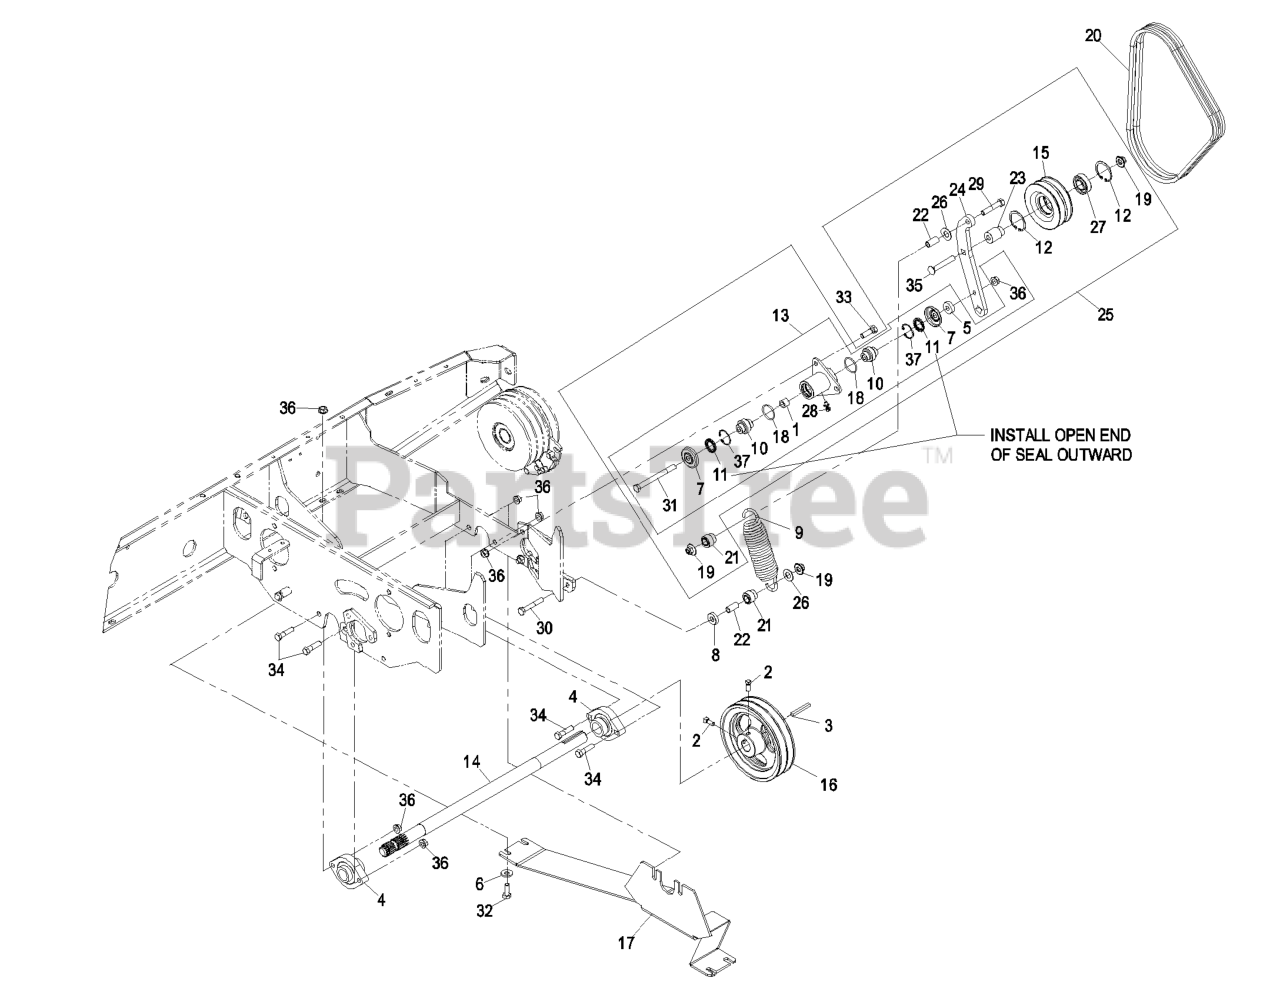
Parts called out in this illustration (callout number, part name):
1	BUSHING-LEVER, LIFT
2	SCREW-SET
3	KEY-SQUARE
4	BEARING-FLANGE
5	SPACER-IDLER
6	WASHER-BELLEVILLE
7	GUARD-TOP
8	SPACER-BRACKET, GUIDE
10	BEARING-SPHERICAL
11	SEAL-LIP, SINGLE
12	RING-RETAINING
13	KIT,'04 XP PUMP IDLER
14	SHAFT, LINE
16	SHEAVE, 2-A
17	GUARD, LINEDRIVE
19	Nut-Nyloc 3/8-16 Flg
20	BELTS,MATCHED A-COG 39.36
21	BUSHING,PLASTIC
23	SPACER,IDLER BEARING
24	Arm, Idler
25	ASM,LINEDRIVE IDLER
26	WASHER-TEFLON
27	BEARING-BALL
28	FITTING-GREASE, 90 DEG
29	SCREW-HH
30	SCREW-HH
31	Bolt-Carriage 3/8-16 X 2 1/4
32	SCREW-HH
33	SCREW-HH
34	SCREW-HH
35	SCREW-CARR
36	NUT-HHF, WHIZ
37	RING-SNAP
